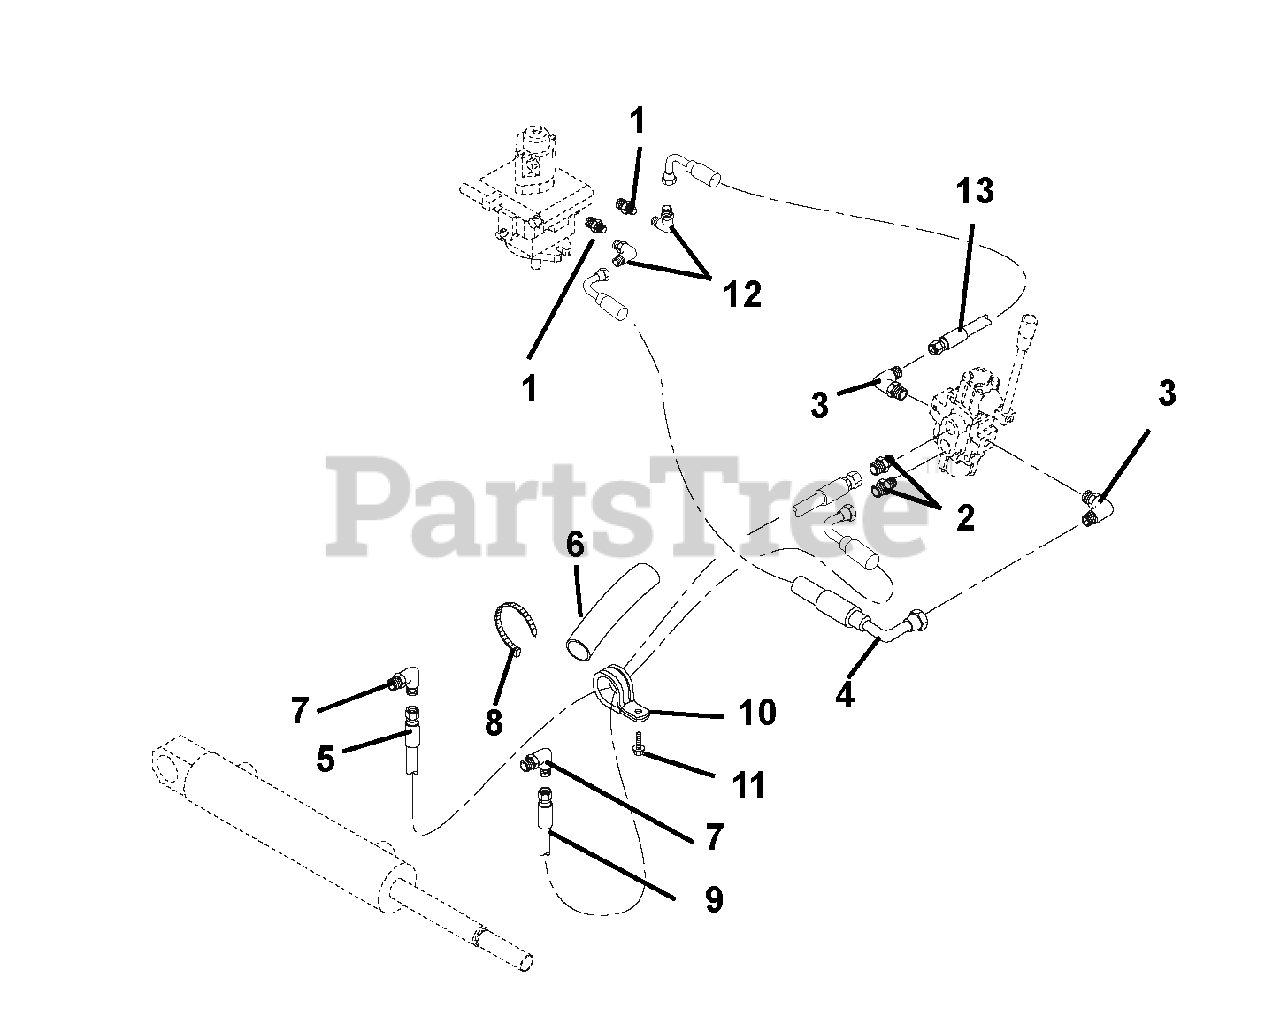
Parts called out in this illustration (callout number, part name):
1	FITTING, HYD (4 F5OLO)
2	FITTING, HYD (4-6 F5OLO)
3	FTG, HYD ELBOW M4F-M8O
4	HOSE,HYD .25-19-2K F04F9-F04F9
5	HOSE,HYD .25-47-2K FO4F0-FO4F0
6	SLEEVE, PROTECTIVE
7	FITTING, HYD (4 C5OLO)
8	CABLE TIE LG 5-1/2
9	HOSE,HYD.25-42-2K F04F0-F04F4
10	CLAMP, COUSHIONED STEEL REV
11	@SCR-TAP .25-20X.50 HWH TR YWZ
12	FTG, HYD ELBOW F4F-M4O
13	HOSE,HYD .25-15-2K F04F9-F04F0
